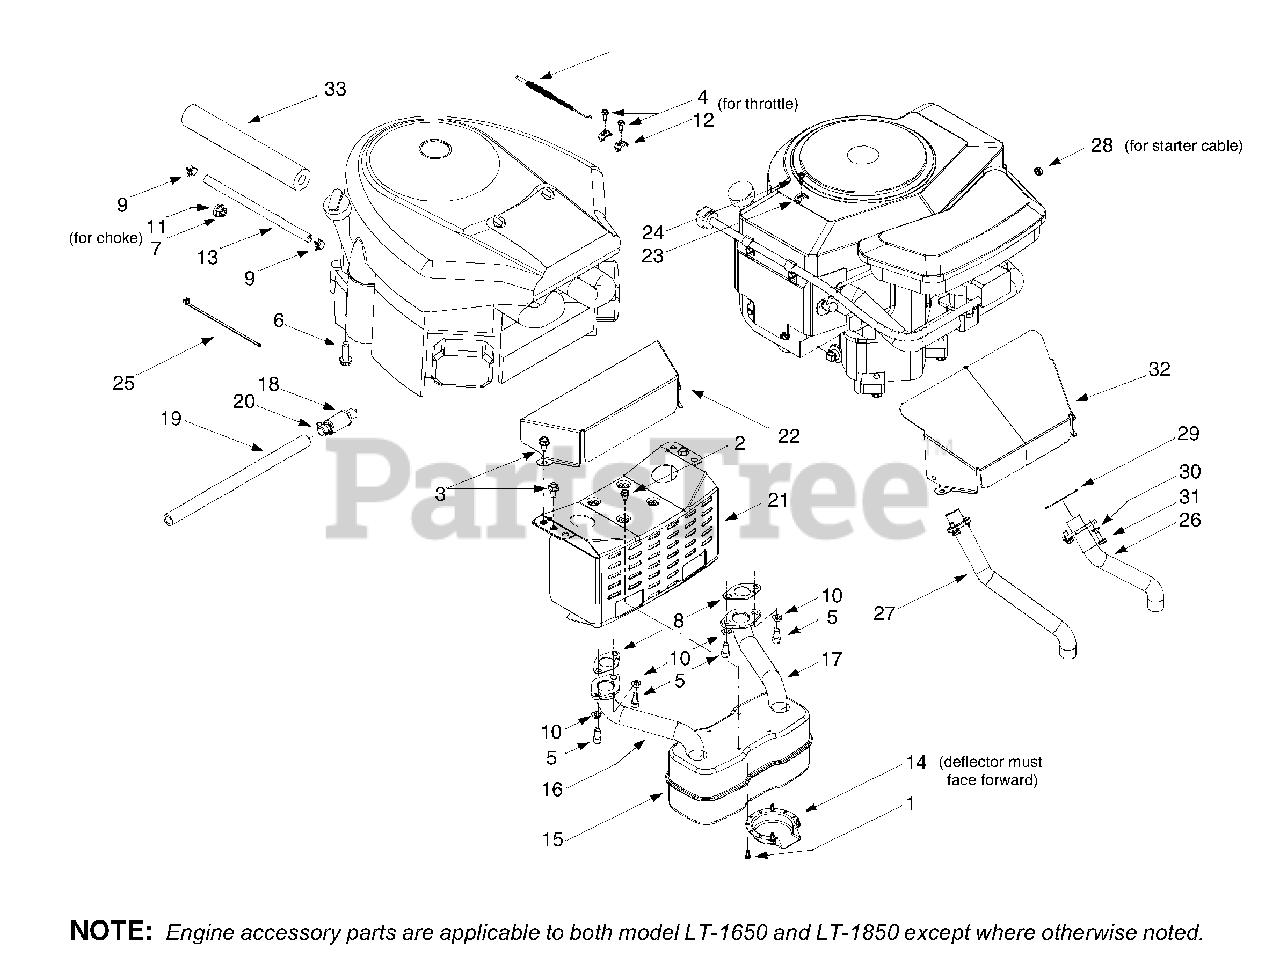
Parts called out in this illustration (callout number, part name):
1	Self-tapping Screw, #8-32 x .375
2	Self-tapping Screw, 1/4-20 x .5
3	Self-tapping Screw, 5/16-18 x .625
4	Screw, #10-32 x .625 (LT-1850)
5	Socket Cap Screw, 5/16-18 x .625
6	Self-tapping Screw, 3/8-16 x 1.25
7	Hex Nut, 3/8-16
8	Exhaust Gasket (LT-1850)
10	Lock Washer, 5/16
11	Lock Washer, .406 x .875 x .059
12	Casing Clamp (LT-1850)
13	Fuel Line Hose
14	Muffler Deflector
15	Muffler, Twin Inlet
16	RH Exhaust Pipe (LT-1850)
17	LH Exhaust Pipe (LT-1850)
18	Oil Drain Valve
19	Oil Drain Hose
20	Oil Drain Cap
22	Engine Heat Shield (LT-1850)
23	Clamp, 9/16 (LT-1650)
24	Screw, #10-16 x .5 (LT-1650)
26	LH Exhaust Pipe (LT-1650)
27	RH Exhaust Pipe (LT-1650)
28	Hex Sems Nut, 1/4-20 (LT-1650)
29	Exhaust Gasket (LT-1650)
30	Lock Washer, 1/4 (LT-1650)
31	Hex Screw, 1/4-20 x .620 (LT-1650)
33	Foam, .625 x 1.5 x 10
